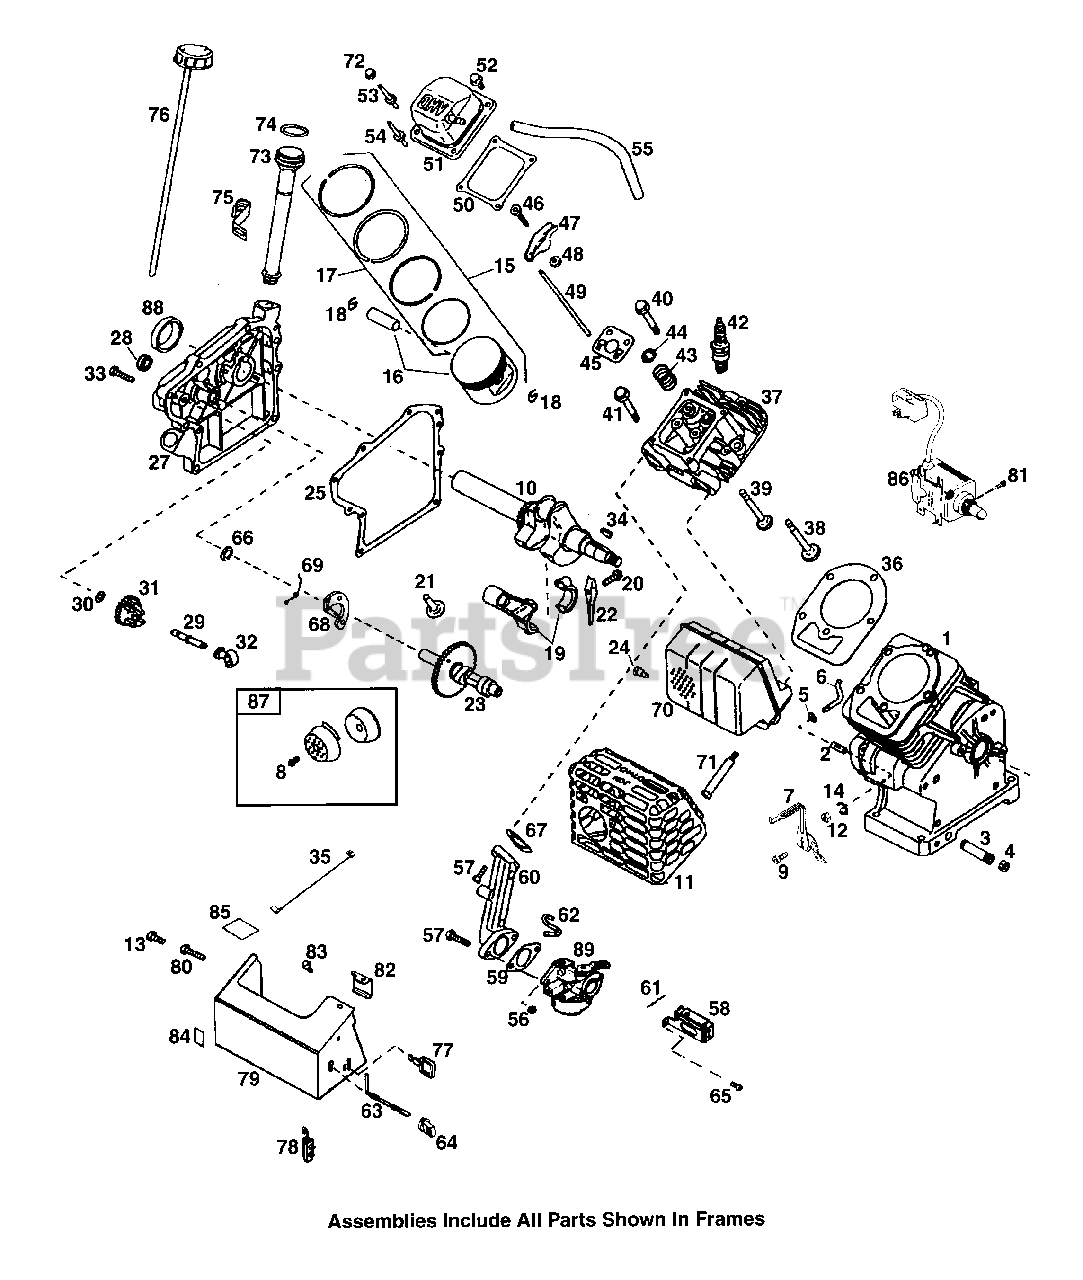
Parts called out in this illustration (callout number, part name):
1	Cylinder
2	Dowel Pin
3	Oil Drain Extension
4	Extension Cap
6	Governor Rod
7	Governor Lever
8	Screw, 10-21 x 1/2"
9	Screw, 10-32 x 63/64"
10	Crankshaft
11	Heat Shield
12	Lock Nut, 10-32
13	Screw, 10-32 x 3/8"
14	Retaining Ring
15	Piston, Pin & Ring Set
16	Piston & Pin Ass'y
17	Ring Set
18	Piston Pin Retaining Ring
19	Connecting Rod Ass'y
20	Connecting Rod Bolt
21	Valve Lifter
22	Oil Dipper
24	Screw, 1/4-20 x 27/32"
25	Cylinder Cover Gasket
28	Camshaft Seal
29	Governor Shaft
31	Governor Gear Ass'y
32	Governor Spool
33	Screw, 1/4-20 x 1-1/4"
34	Flywheel Key
35	Ground Wire
36	Cylinder Head Gasket
37	Cylinder Head
38	Exhaust Valve
39	Intake Valve
40	Screw, 5/16-18 x 1-1/2"
41	Screw, 5/16-18 x 2-41/64"
42	Resistor Spark Plug (N4C)
43	Valve Spring
44	Valve Spring Cap
45	Push Rod Guide
46	Rocker Arm Stud
47	Rocker Arm
48	Nut, 1/4-28
50	Rocker Arm Cover Gasket
51	Rocker Arm Cover
52	Screw, 1/4-20 x 31/64"
55	Breather Tube
56	Nut, 1/4-20
57	Screw, 1/4-20 x 1"
58	Choke Bracket
59	Carb. to Intake Pipe Gasket
60	Intake Pipe
61	Choke Spring
62	Throttle Link
63	Choke Rod
64	Choke Knob
65	Screw, 10-32 x 1/2"
67	Intake Pipe Gasket
68	Compression Release Weight
69	Compression Release Spring
70	Muffler
71	Screw, 1/4-20 x 2-9/32"
72	Nut & Lock Washer
73	Oil Fill Tube
74	110" Ring
75	Fill Tube Clip
77	Ignition Key
79	Carburetor Cover
80	Screw, 10-32 x 1/2"
81	Screw, 1/4-20 x 5/8"
82	Carburetor Cover Bracket
83	Screw, 10-32 x 1/2"
84	Primer Decal
85	Warning Decal
86	Electric Starter Motor (110 Volt)
87	Spark Arrestor Kit
89	Carburetor
